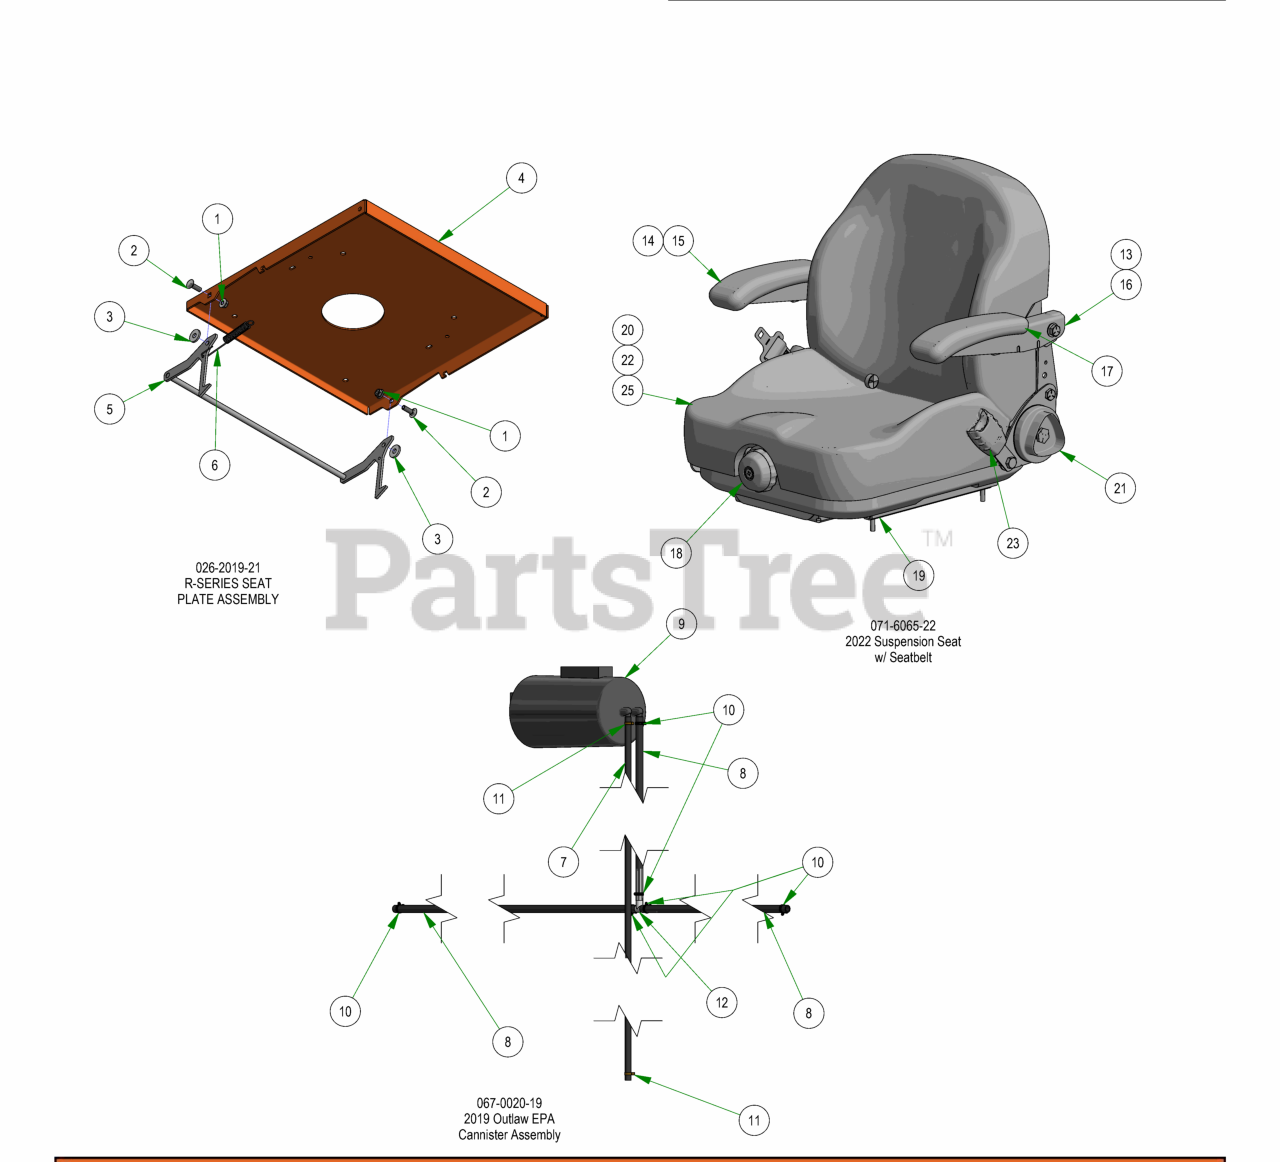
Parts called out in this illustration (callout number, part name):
1	5/16-18 NYLON INSERT FLANGE LOCKNUT ZINC
2	5/16-18 X 1 CARRIAGE BOLT (GR.8) ZINC
3	.360 ID X .983 OD X .120 THICK FLAT WASHER NYLON
4	R-SERIES SEAT PLATE
5	Seat Latch Rod Assembly
6	Brake Spring
7	3/16" Vinyl Tubing, 66" Long
8	1/4" Vinyl Tubing 38" Long
9	Carbon Canister
10	3/16 Vinyl Clamp
11	3/16" Vinyl Hose Clamp
12	fuel line T
13	Set of Armrests-SS Front Adj
14	RH Armrest-Selfskin Front Adj
15	Black Selfskin-Arm Pad Only
16	LH Armrest-Selfskin Front Adj
17	Black Selfskin-Arm Pad Only
18	Weight Adjust Indicator Knob Assy
19	4" Single Locking Track Kit
20	Delta Plunger Switch - N.O.
21	Recliner Adjustment Knob-New
22	Bellows w/Hardware
23	2" Retractable Belt Kit w/Spacers
24	Back Cover for I3M - Recl - Logos
25	Cushion Cover Kit for I3M-Logo
